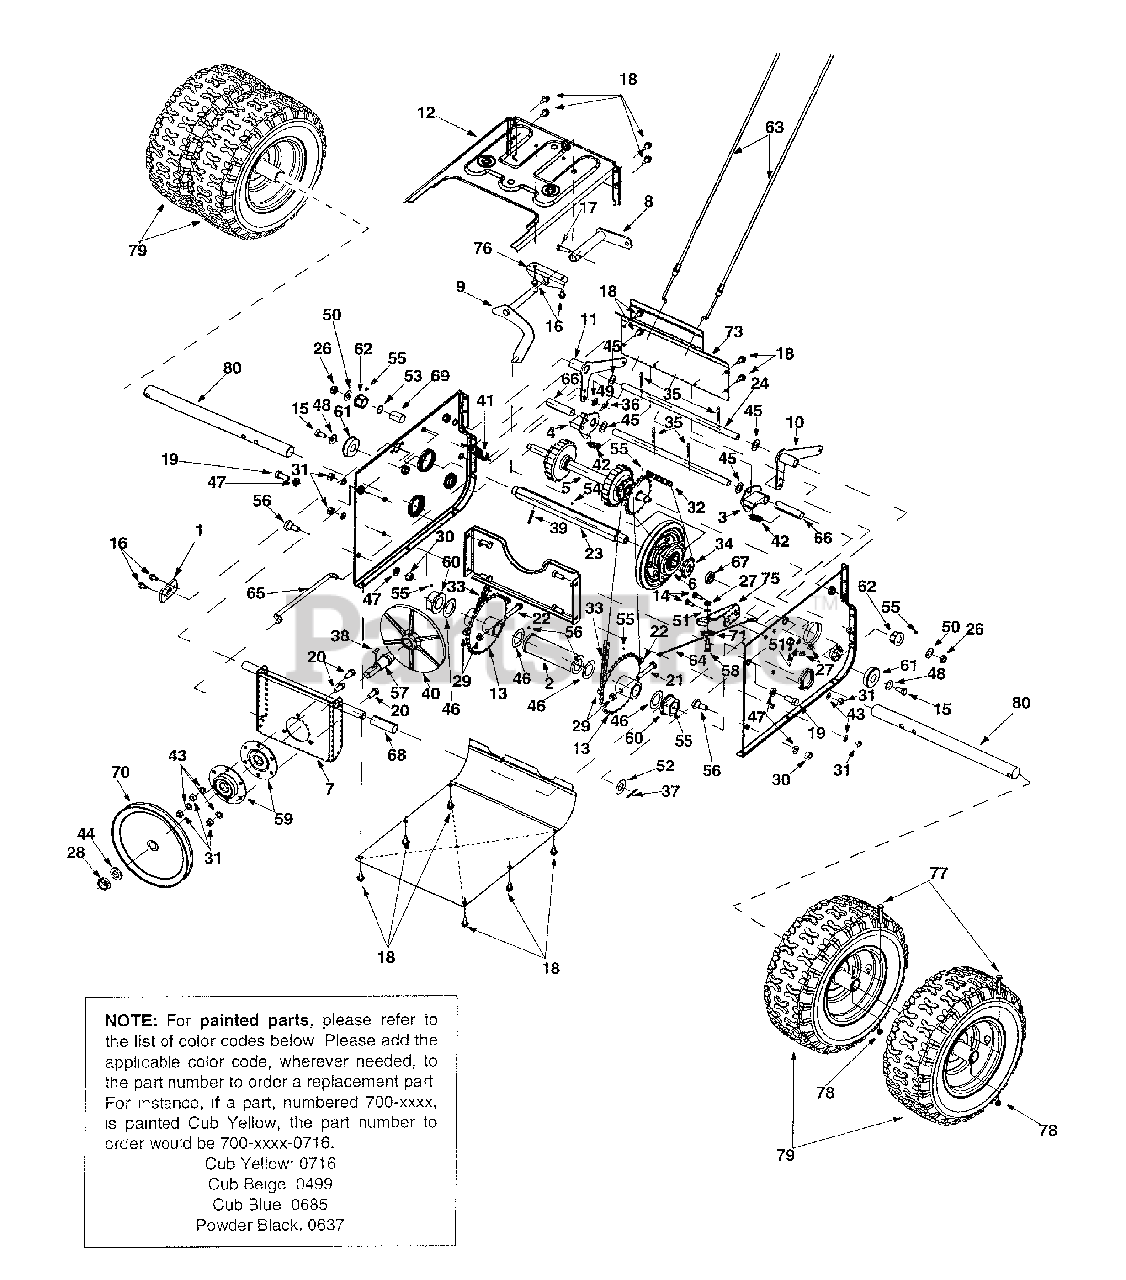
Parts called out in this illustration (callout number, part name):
1	Support Bracket: Pivot
2	Bush Assembly
3	Dogg Assembly LH
4	Dogg Assembly RH
5	Shift Assembly
6	Wheel Bearing Assembly
10	Auger Actuator Bracket Assy.
14	Hex Screw 1/4-28 x .625"
15	Hex Screw 5/16-18 x .625"
16	TT Screw 1/4-20 x .5"
17	TT Screw 1/4-20 x 1"
18	TT Screw 1/4-20 x .625"
19	Hex Screw 3/8-16 x .880"
20	Hex Screw 5/16-18 x .75"
21	Hex Screw 5/16-18 x 2"
22	Hex Screw 5/16-18 x 1.75"
23	Hex Shaft: Drive
24	Actuator Shaft
27	Hex Nut 1/4-28
28	Jam Lock Nut
29	Hex Lock Nut
30	Hex Nut 3/8-16
31	Hex Nut 5/16-18
35	Hairpin Clip
36	Hairpin Clip
37	Cotter Pin
38	Key
39	Roll Pin
40	Drive Plate
41	Extension Spring
42	Extension Spring
43	Lock Washer 5/16
44	Lock Washer 5/8
45	Flat Washer
46	Flat Washer
47	Lock Washer
48	Beleville Washer
49	Flat Washer
50	Flat Washer
51	Lock Washer
52	Flat Washer
53	Flat Washer
54	Lubricant
56	Shoulder Screw
57	Spindle: Drive Plate
58	Shoulder Screw 1/4-28 x .375"
59	Bearing Housing Assembly
60	Flange Bearing
61	Ball Bearing
62	Hex Flange Bearing
63	Steer Cable
64	Idler Cable: Auger
65	Clutch Rod: Drive
66	Split Spacer
67	Spacer
68	Split Spacer
70	Drive Pulley
71	Roller Cable
77	Hex Screw 5/16-18 x 2"
80	Axle: Wheel
